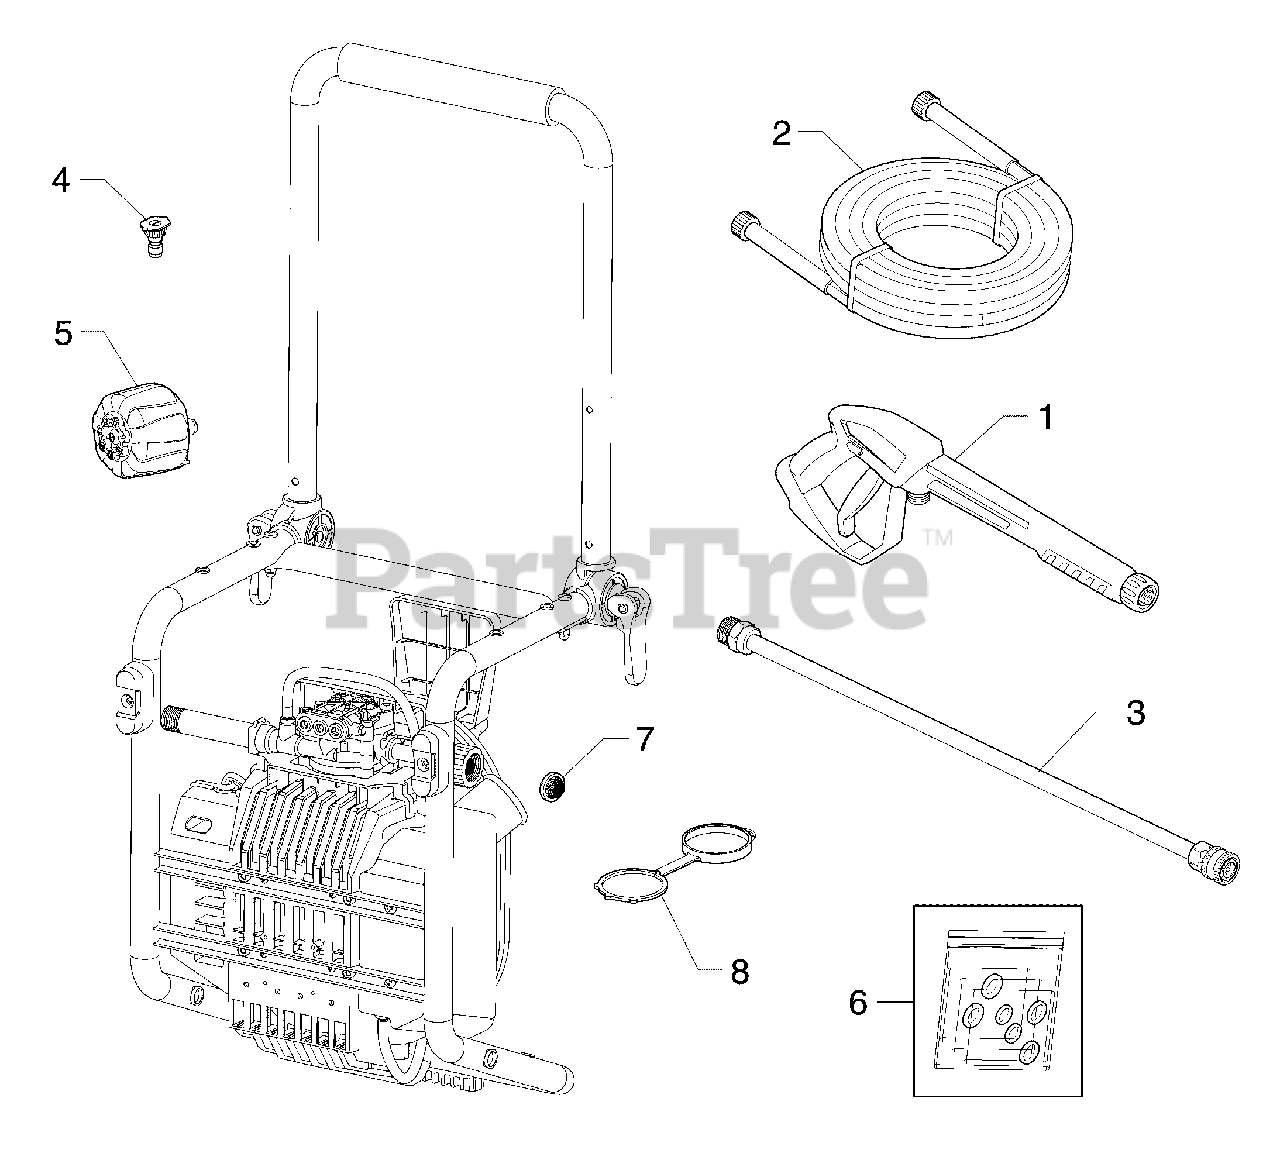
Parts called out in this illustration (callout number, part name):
4	QUICK CONNECT
5	NOZZLE
7	FILTER-GARDEN HOSE
